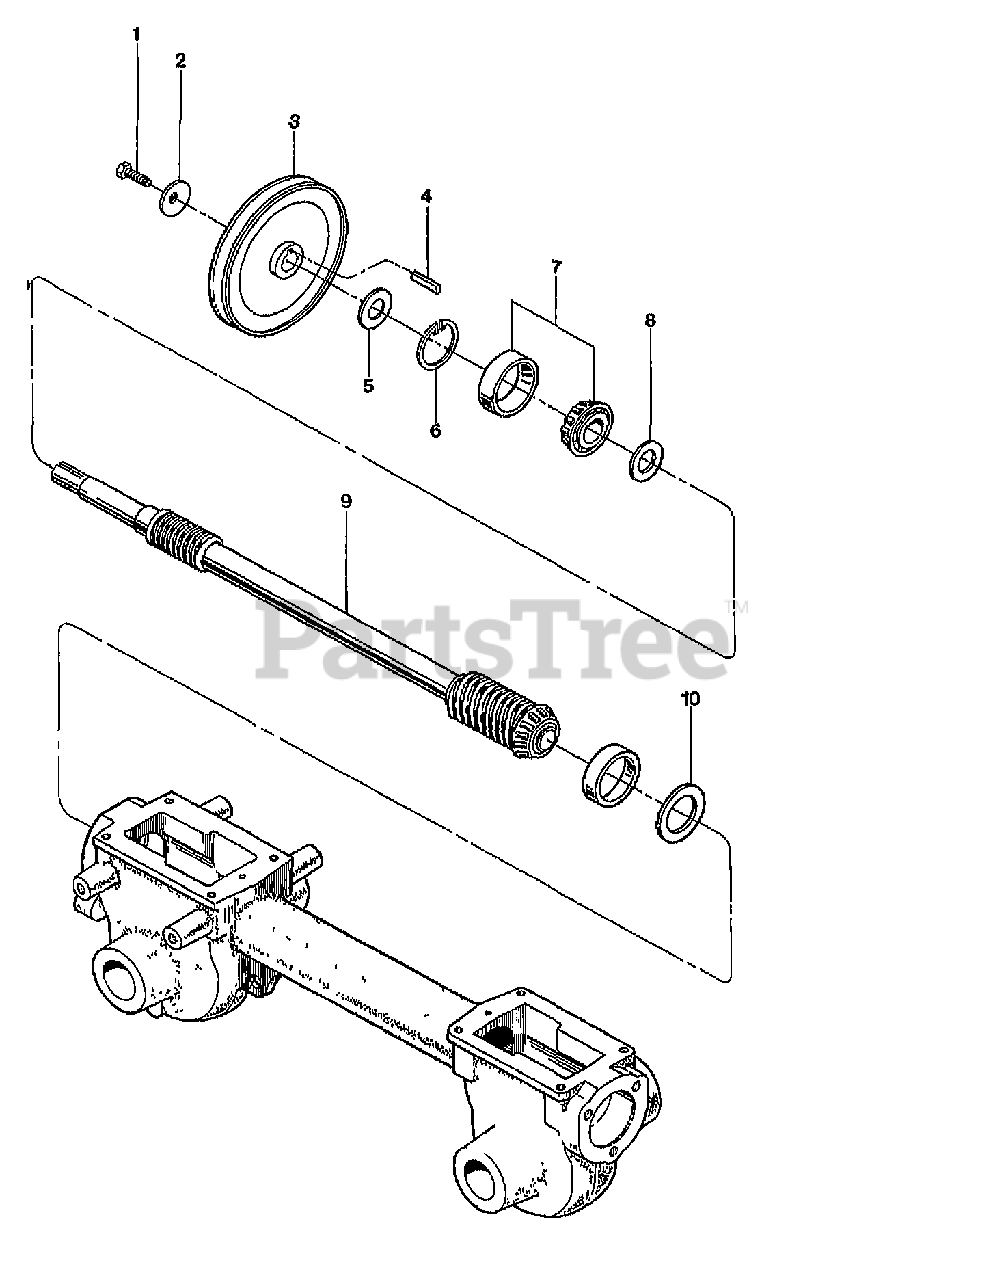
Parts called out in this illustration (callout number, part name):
1	SCR-HH 5/16-24X.75 G5 ZP
2	WASHER-.827X.331X.098
3	PULLEY-TRANSMISSION
4	KEY-.188 SQX1.0
5	WASHER-SHLDR HARDENED
6	RING-RETAINING 5000-181
7	KIT-BRG CONE&RACE-DRIVESHAFT
8	WASHER-#1.25X.75X.06
9	DRIVESHAFT-MACH
9	ASSM-DRIVESHAFT TUFFY {12155}
10	SHIM-1.75X1.5X.01 AS REQ'D
10	SHIM-1.75X1.5X.03 AS REQ'D
10	SHIM-1.75X1.5X.005 AS REQ'D
10	SHIM-1.75X1.5X.062 AS REQ'D
10	SHIM SET-DRIVESHAFT-HORSE
